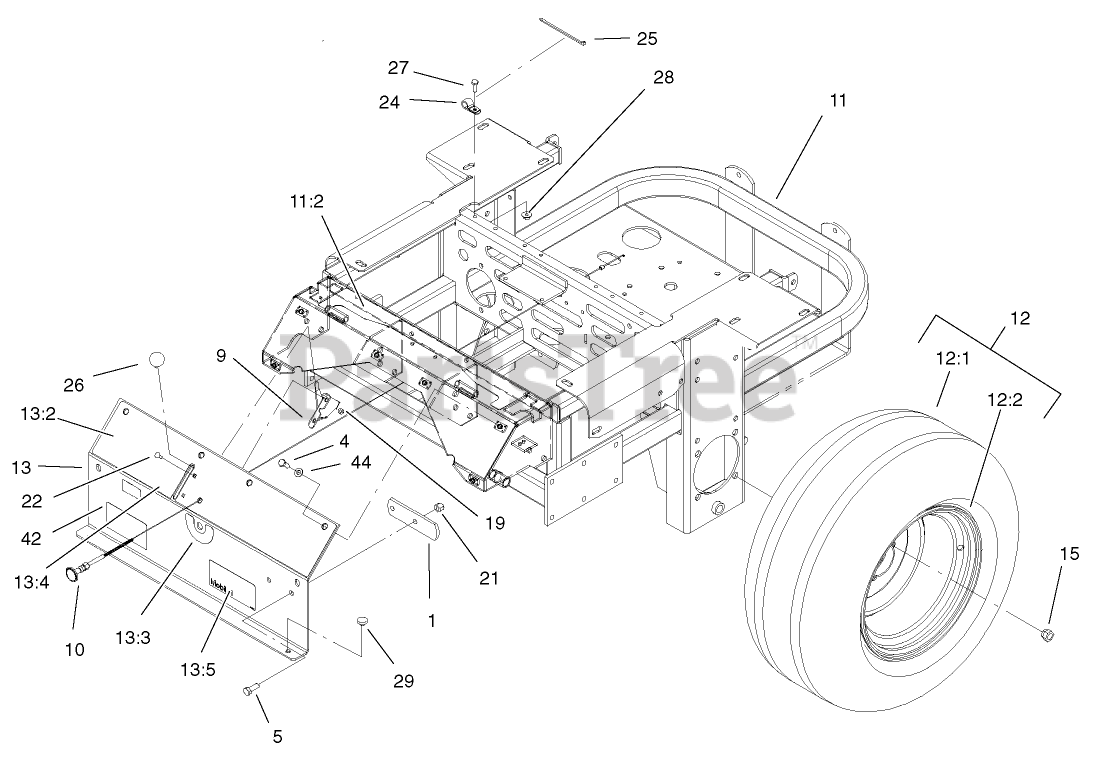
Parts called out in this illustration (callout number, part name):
1	STOP-BRAKE, PARK
4	SCREW-HH
5	SCREW-HH
9	THROTTLE CABLE ASM
10	CONTROL-CHOKE
11	Main Frame ASM
11:2	DECAL-CONSOLE, TOP
12	WHEEL AND TIRE ASM
12:2	WHEEL RIM
13	CONSOLE ASM
13:2	DECAL-PANEL, CONTROL
13:3	DECAL-VALVE, FUEL
13:4	DECAL-PROTECTION, EAR
13:5	DECAL-MOBIL 1
15	NUT-LUG
19	NUT-LOCK, NI
21	NUT-LOCK, NI
22	BOLT-CARR
24	CLIP-LOOM
25	TIE-PLASTIC
26	KNOB-BALL
27	SCREW-HH
28	NUT-HF
29	BUMPER
42	Decal-Z287l
44	WASHER-PLAIN
